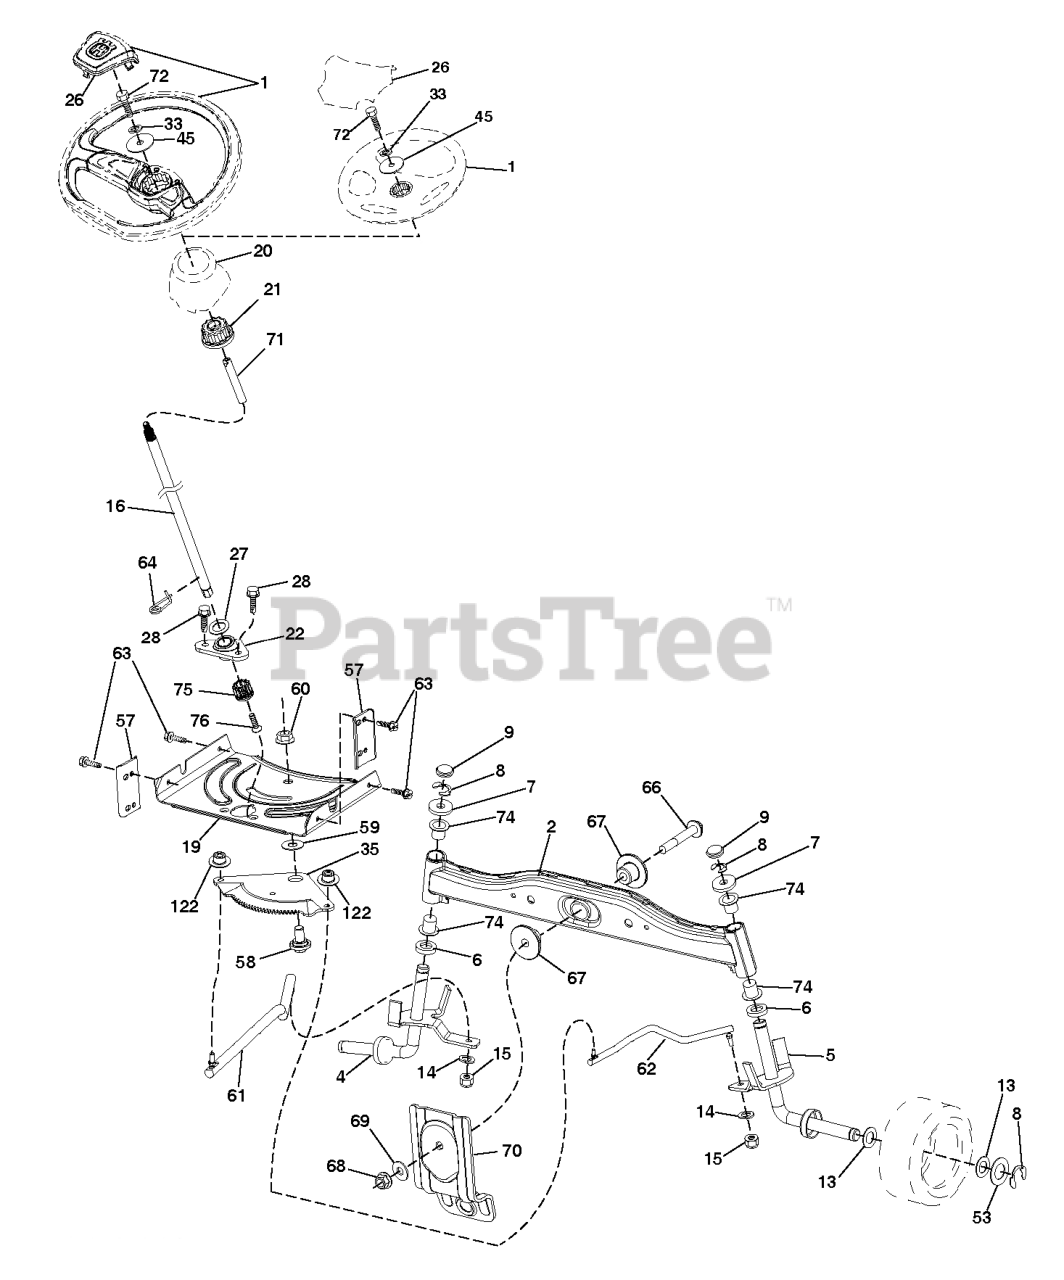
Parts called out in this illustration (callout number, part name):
1	WHEEL.STEERING.HUSQ.PREM.HRDRM
1	Service Kit
2	AXLE HALF ASM-WELDED
4	SPINDLE.WELDED.LH.15"TEX
5	SPINDLE.WELDED.RH.15"T
6	WASHER THRUST
9	CAP.SPINDLE.BLACK
15	NUT CROWNLOCK 3/8-24
16	3 HIGH.SHAFT-ZINC.PLATED
19	PLATE.STEER.DDL.NLT/NG
20	STEERING.BOOT.HUSQ.LT
21	ADAPTER, WHEEL STNG..
22	BEARING.SHAFT.STEER.LOWER.625
26	Steering
26	INSERT.CAP.WHL.STRG.HUSQ.PREM
27	WASHER LT
28	SCREW, 3/8-16X3/4
33	WASHER SPRING LOCK WASHER WITH
33	WASHER.LOCK.HVY.HLCL.SPR.5/16
35	GEAR.SECTOR.PLATE.DDL.
45	WASHER.11/32
53	WASHER.HARDENED
57	BRACKET.UPSTOP.TEX
58	BOLT.SHOULDER.SECTOR.P
59	WASHER.THURST.SECTOR.S
60	NUT FLANGE LOCK 5/8-11
61	DRAGLINK.LH.BALLSTUD.D
62	DRAGLINK.RH.BALLSTUD.D
63	SCREW
64	RETAINER.CLIP.SPRING.S
66	BOLT HEX FGHD 7/16-14 X 3 SERR
67	BUSHING.PM.FRONT AXLE
68	NUT.LOCK.FLANGE.7/16
69	WASHER.1.5X.505X.118
70	BRACKET.FRT.DECK.SUSP.RR.MT431
71	SHAFT.EXTEN.STRG.SPLINE
72	BOLT 5/16-18 X 4 W/PATCH
74	BEARING.STEERING.COLUMN
75	KIT.SRVC.STEERINGSHAFT.PINION
76	SCREW HEAD SOCKET LRVB
122	CAP.GEAR.SECTOR.TEX
